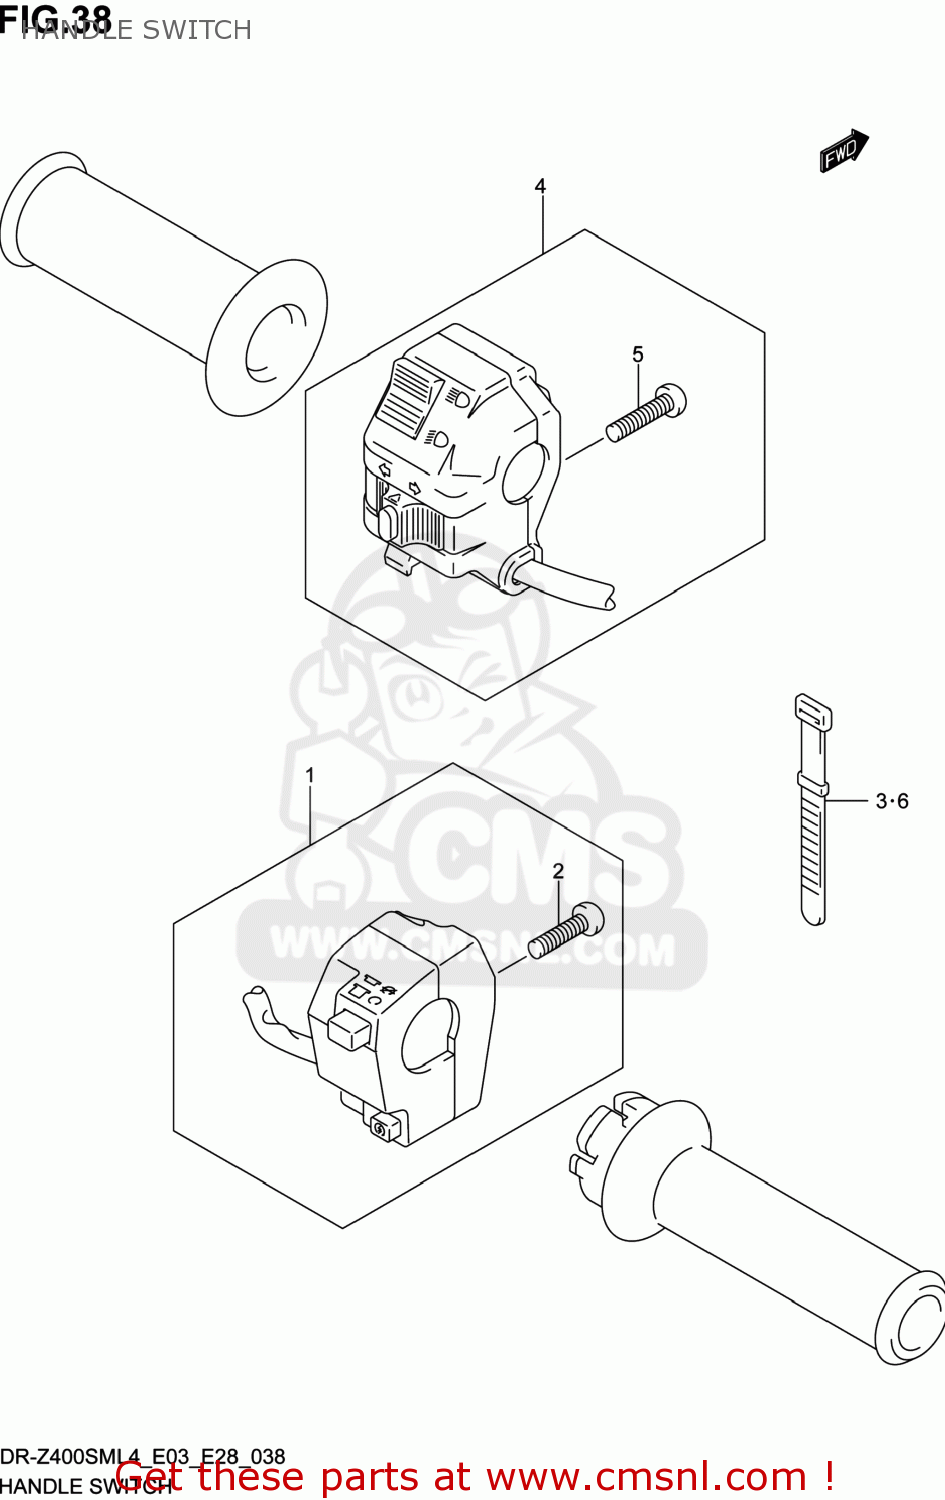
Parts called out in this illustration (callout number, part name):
1	SWITCH ASSY,HANDLE,R
2	SCREW
3	CLAMP(L:120)
4	SWITCH ASSY,HANDLE,L
5	SCREW
6	CLAMP(L:120)
